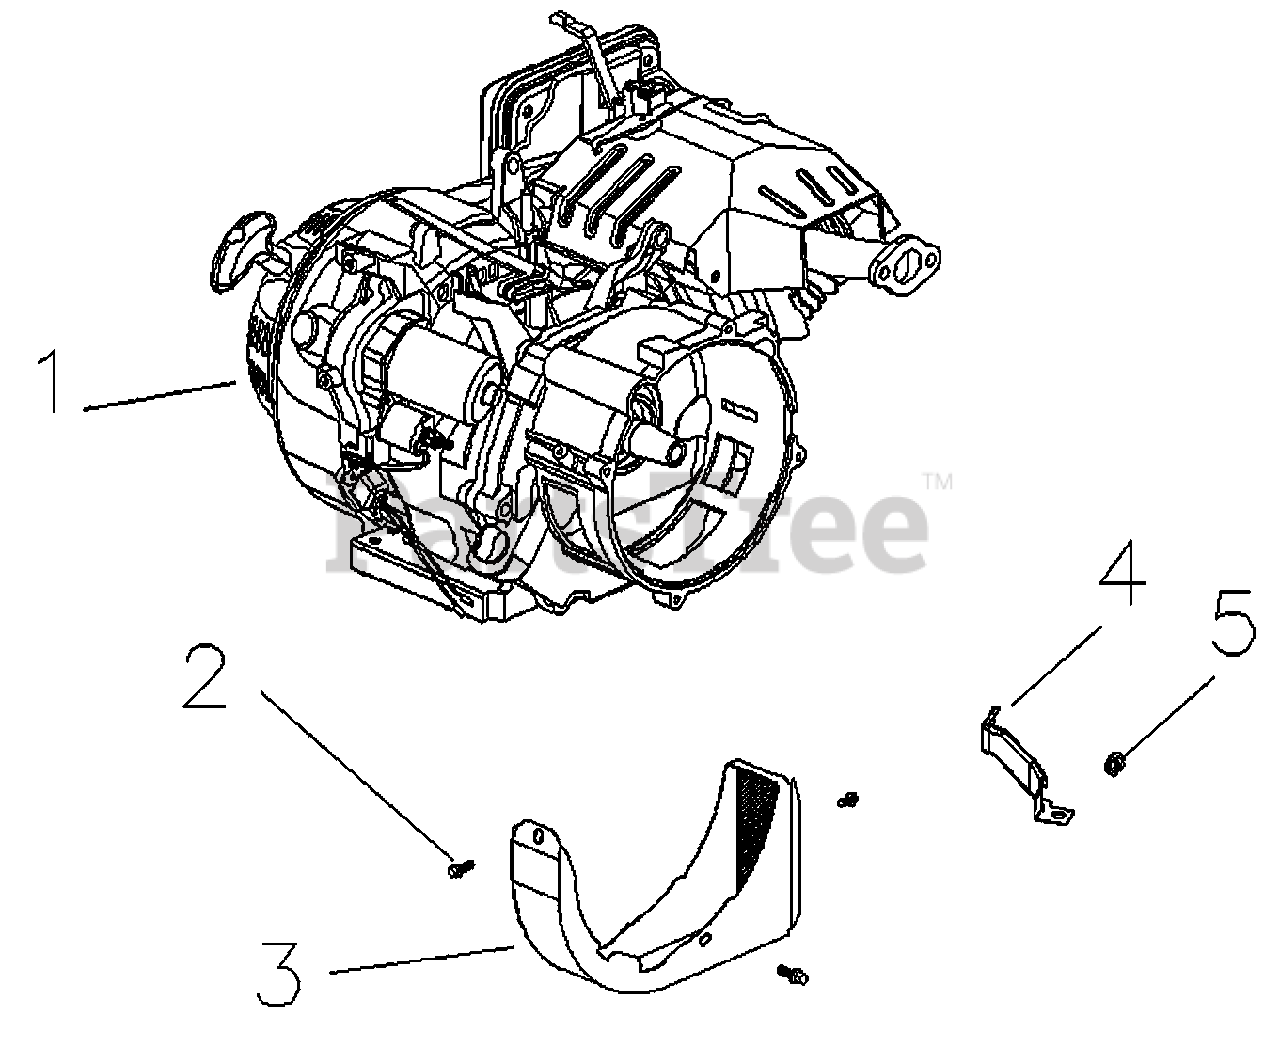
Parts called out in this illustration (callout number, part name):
1	ENGINE G390FDA
2	BOLT, FLANGE M5*10
3	SCROLL, HONEYWELL
4	BRACKET,AIR CLEANER
5	NUT, FLANGE M6
